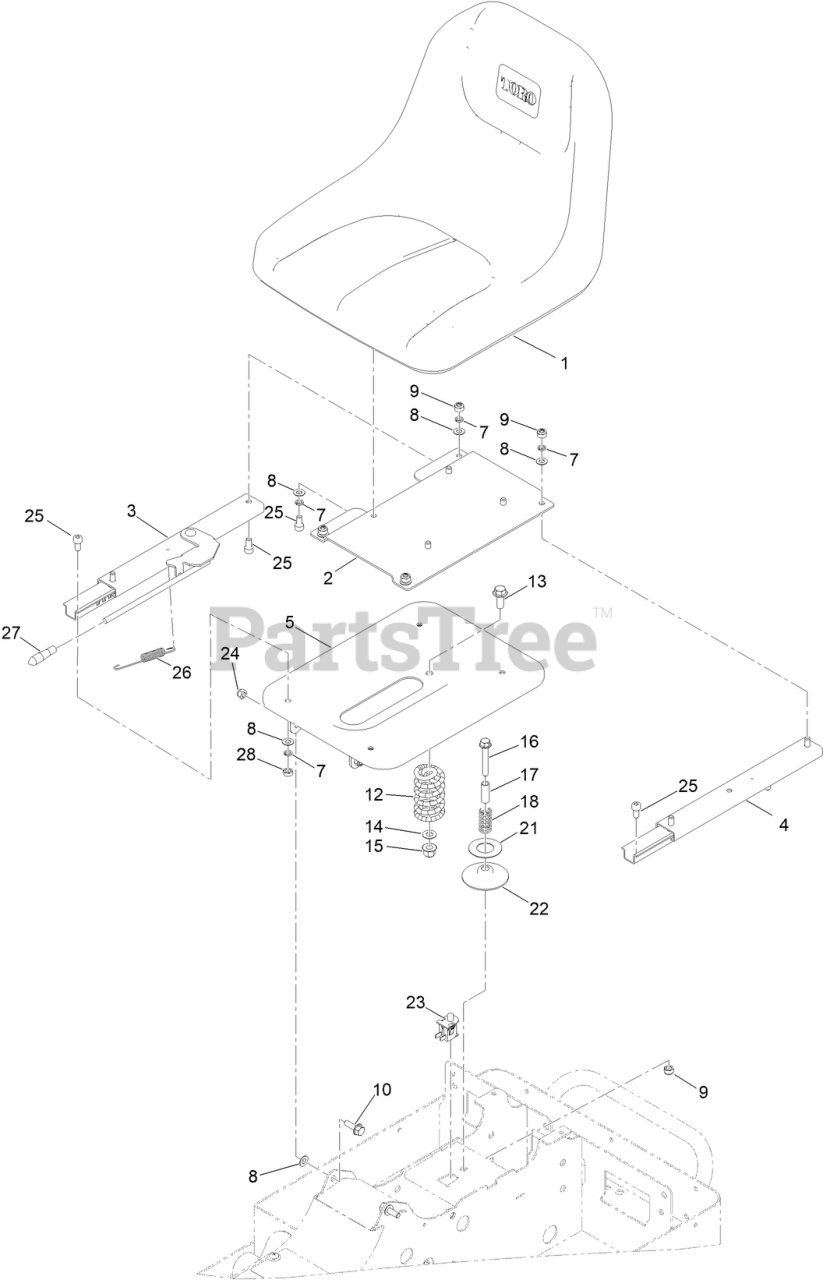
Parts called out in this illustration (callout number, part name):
2	MOUNTING PLATE, SEAT
3	SEAT SLIDE ASM, RH
4	SEAT SLIDE ASM, LH
5	SEAT BASE, ASM
7	WASHER-SPRING
8	WASHER-PLAIN
9	NUT-HEX, NI
10	SCREW-HHF
12	SPRING, SEAT
13	SCREW-HHF
14	WASHER-PLAIN
15	NUT-FLANGE, NI
16	SCREW-HHF
17	SHAFT, SPRING
18	SMALL SPRING, SEAT
21	WASHER
22	PLATE, SPRING SEAT
23	SEAT SENSOR
24	NUT, SEAT
25	BOLT SEAT, SLIDE MOUNT
26	ADJUSTMENT SPRING, SEAT
27	ADJUSTMENT LEVER CAP, SEAT
28	NUT-HEX
